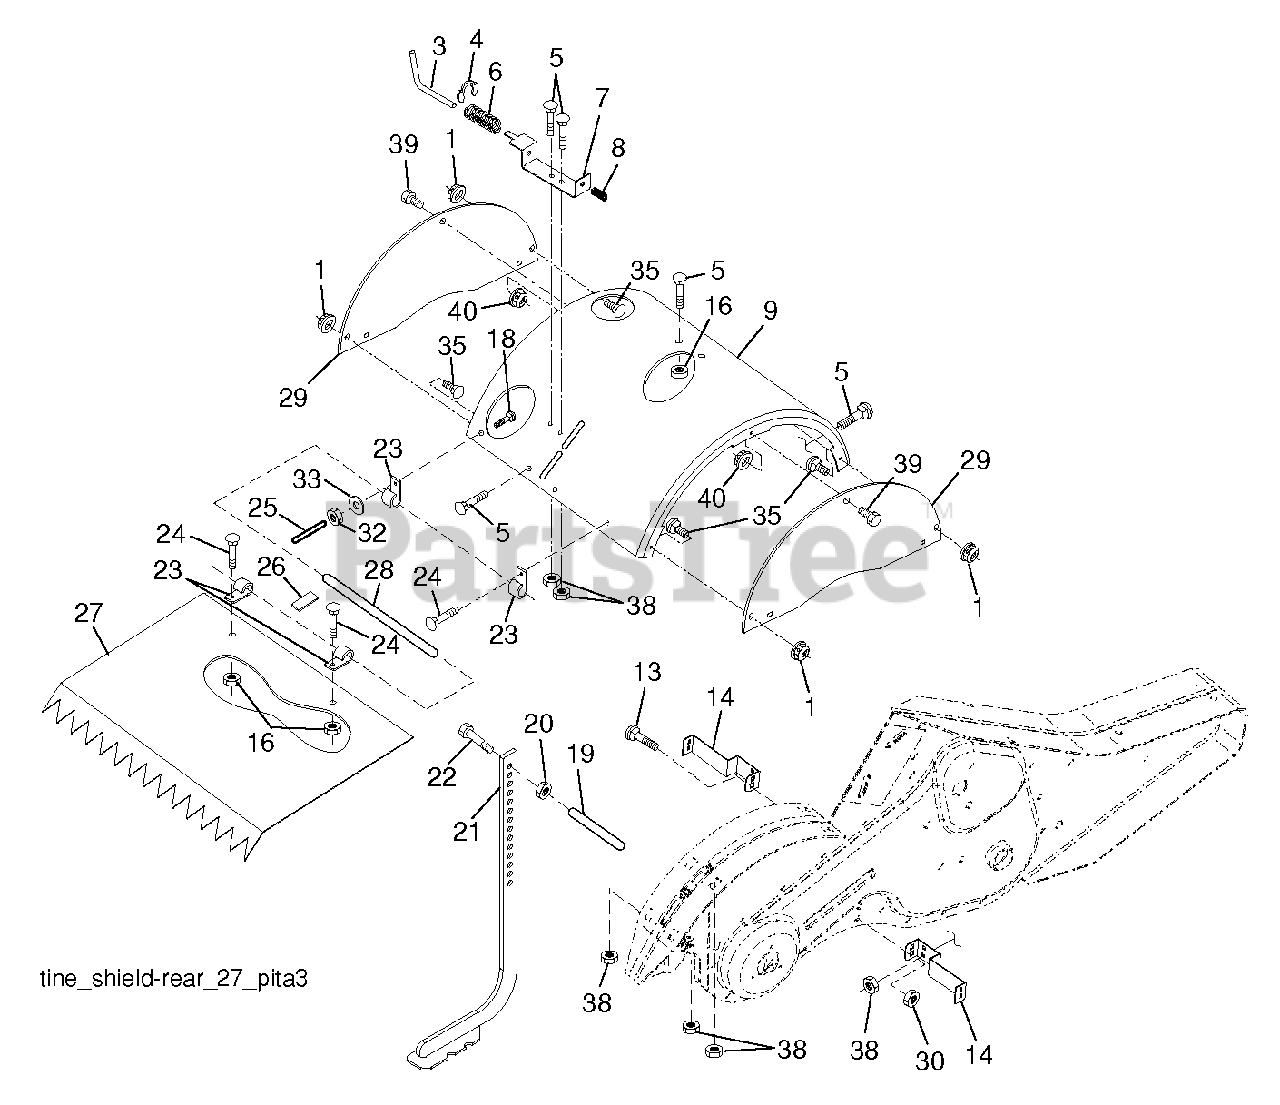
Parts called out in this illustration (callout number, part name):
1	NUT.FLANGE.5/16
3	STAKE PIN TI
4	RING, KLIP
5	BOLT, RDHD SQNK 5/16-18 X 3/4
6	SPRING TI
8	SPRING CRT
9	SHIELD.TILLER.TINE.YELLOW
13	BOLT.CARRIAGE.5/16-18
16	NUT T
19	GRIP CRT
20	NUT.HEX.3/8-16UNC
22	BOLT.375-16
23	HINGE CRT
26	PAD IDLER TI
27	SHIELD.TILLER.LEVELING.YELLOW
28	PIN.HINGE.TILLER
29	SHIELD.SIDE.PNT.421
30	LOCKNUT-FLANGE 5/16-18
32	NUT
33	LOCKWASHER
35	BOLT
39	BOLT.HEX.HD.WASHER.5/16-18X.75
40	NUT.SPEED.5/16-18
